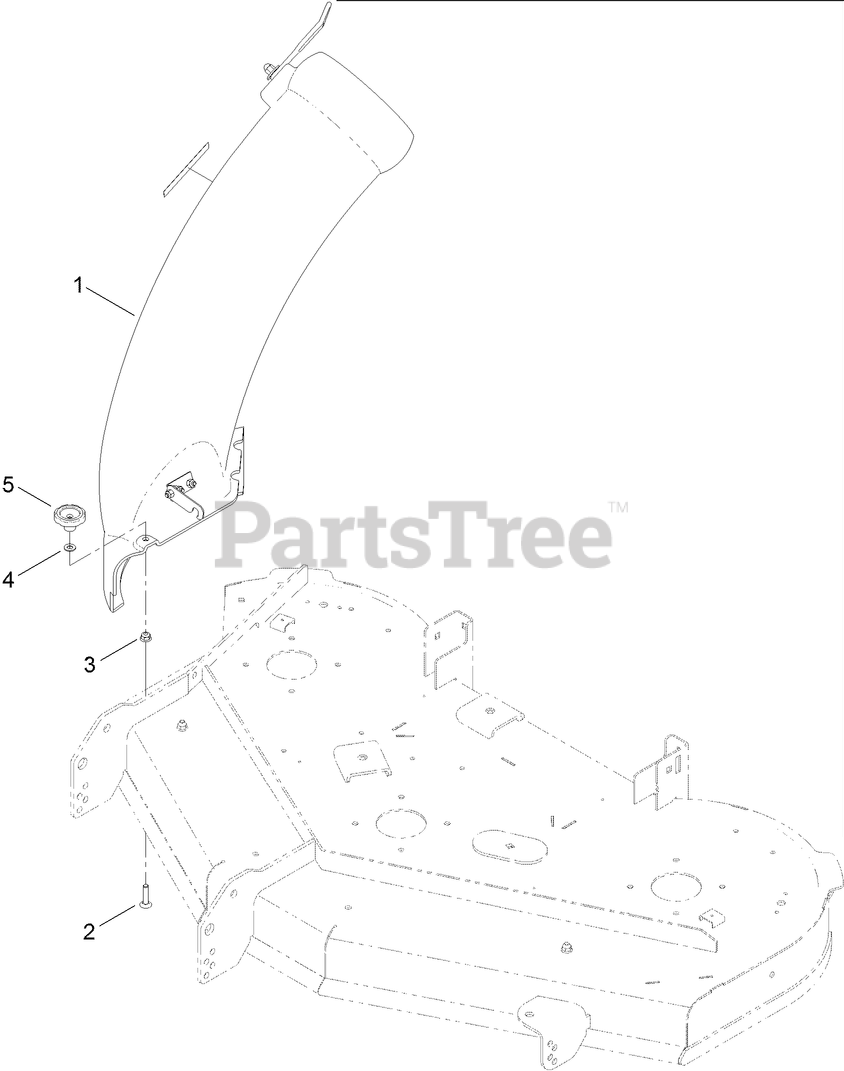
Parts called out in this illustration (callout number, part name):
1	50 INCH CHUTE ASM
2	SCREW-CARR
3	NUT-HF, NI
4	WASHER-PLAIN
